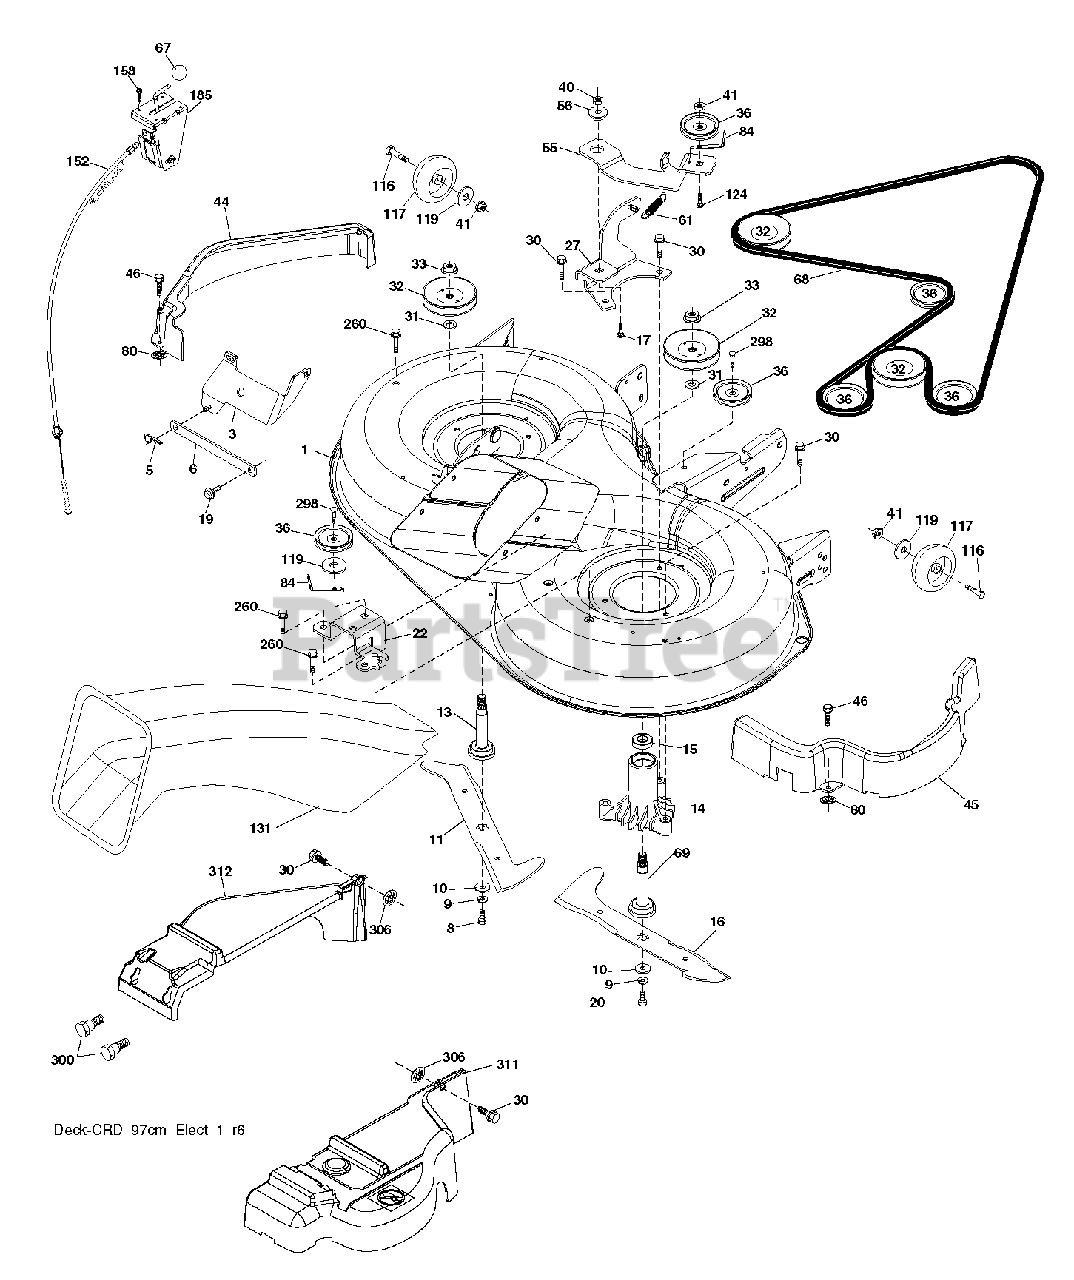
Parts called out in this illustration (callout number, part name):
3	BRACKET.ASM.BAR.SWAY.CHASS
5	RETAINER-SPRNG RB
6	BAR SWAY
9	LOCKWASHER
10	WASHER.BLADE
11	BLADE.3N1.LH.CRD.97
13	SHAFT ASM VENT
14	HSG MANDREL
16	BLADE.3N1.RH.CRD.97
17	BOLT.3/8-14X1.25
19	BOLT SHD 5/16-18
22	BRACKET.SUPT.IDLER.REAR.RH
27	BRACKET.ASM.SUSP.REAR.RH.
30	SCREW, WASHER HEAD
31	WASHER.SPACER.MANDREL
32	PULLEY MANDREL
33	NUT.FLANGE.LOCK.TOP
36	PULLEY.IDLER.4.25
40	LOCKNUT
41	NUT LOCK FLG 3/8-16 UNC
46	SCREW.1/4-20X5/8
56	SPACER.RETAINER.MOWER
67	KNOB T (3/8 HOLE)
68	BELT.DRIVE.CRD.97.2010
69	SHAFT.ASM.W/LWR.BRG.RH.THREAD
80	PALNUT 1/4
84	KEEPER, BELT IDLER
116	BOLT.SHOULDER.3/8-16X3-5/8
117	WHEEL. GUAGE RALLY
124	BOLT.3/8-16X1.50
131	CHUTE BAGGER
158	SCREW
185	HEAD ASM. CABLE CLUTCH
260	SCREW 3/8-16X1/2
298	SCREW LT
300	BOLT.SHOULDER
